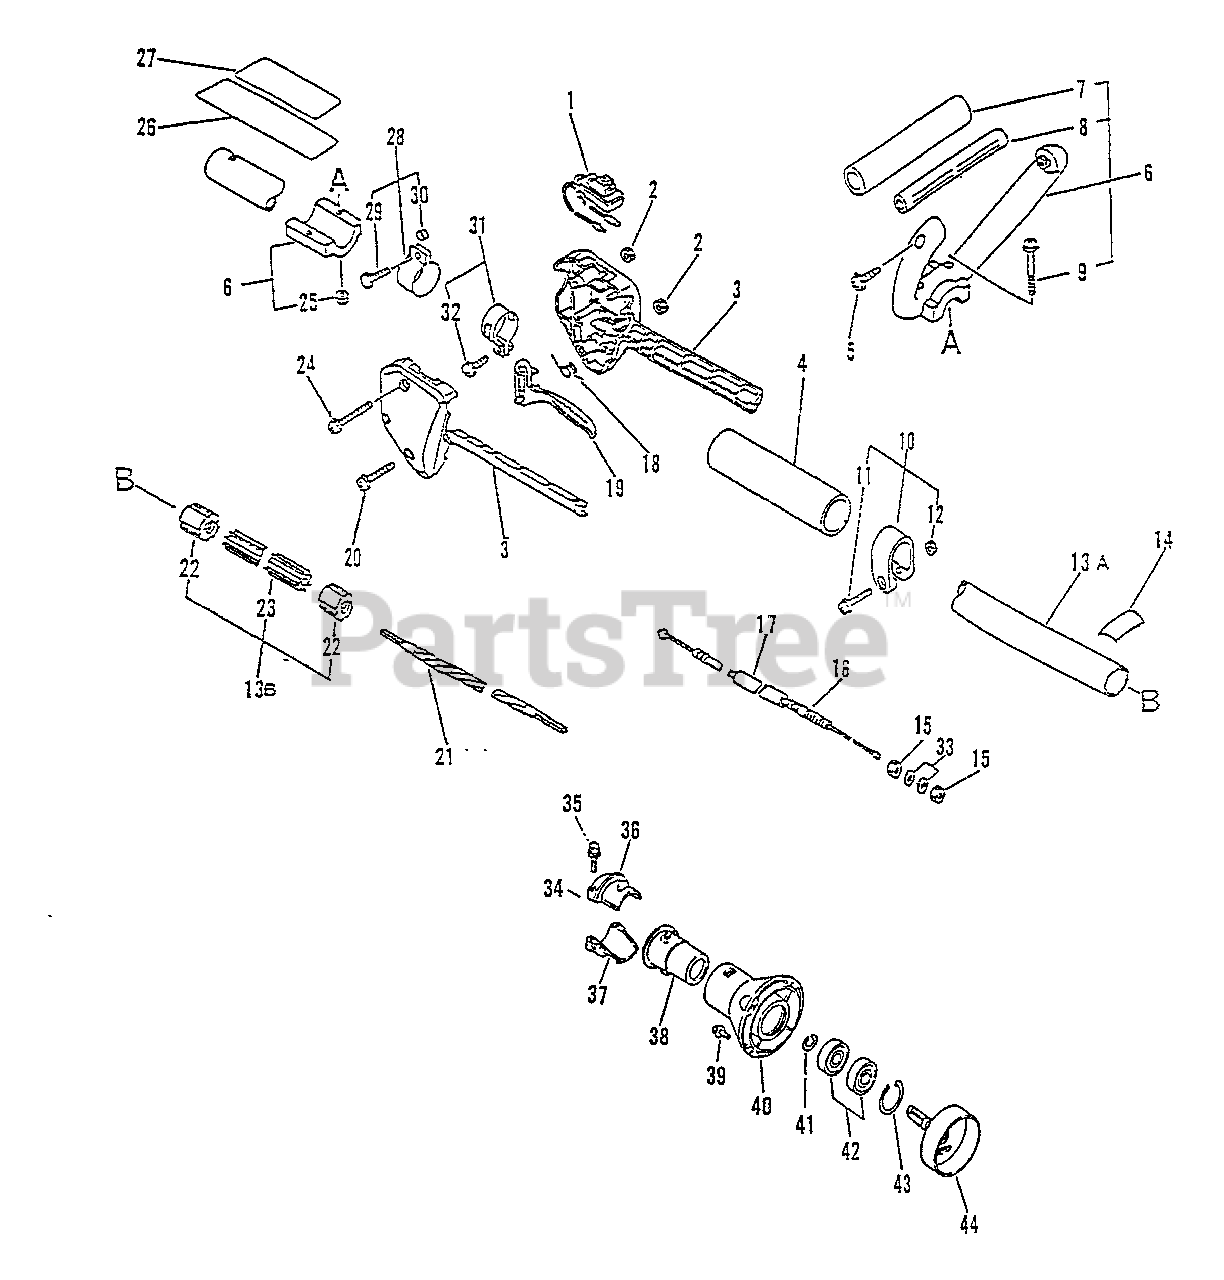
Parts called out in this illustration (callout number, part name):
1	SWITCH, ON-OFF
2	NUT M5
3	HANDLE KIT, CONTROL
4	GRIP, HANDLE
5	SCREW 5×30
6	LOOP HANDLE ASSY
7	GRIP, HANDLE
9	SCREW 6×25
10	CLAMP KIT
11	SCREW 5×30
12	NUT M5
13	MAIN PIPE ASSY 25×1500
14	LABEL - ALIGNMENT
16	CABLE, THROTTLE
17	TUBE - VINYL
18	SPRING, TORSION
19	TRIGGER, THROTTLE
20	SCREW 5×25
21	DRIVESHAFT - FLEXIBLE L= 1522
23	LINER, FLEXIBLE 21.6×1420
24	SCREW 5×35
25	NUT, HEX M6
27	LABEL - CAUTION
28	HOOK
29	BOLT 5×18
30	SPACER, GUARD
31	CLAMP KIT
32	SCREW 5×14
33	WASHER 6.5×11.5×0.8
34	HOLDER KIT
35	BOLT - 5×25
36	HOLDER, MAIN PIPE - UPPER
39	SCREW 5×16
40	CASE, CLUTCH - GRAY
41	RING, RETAINING - 12
42	BEARING, BALL 6001
43	RING, SNAP 28
44	DRUM, CLUTCH
